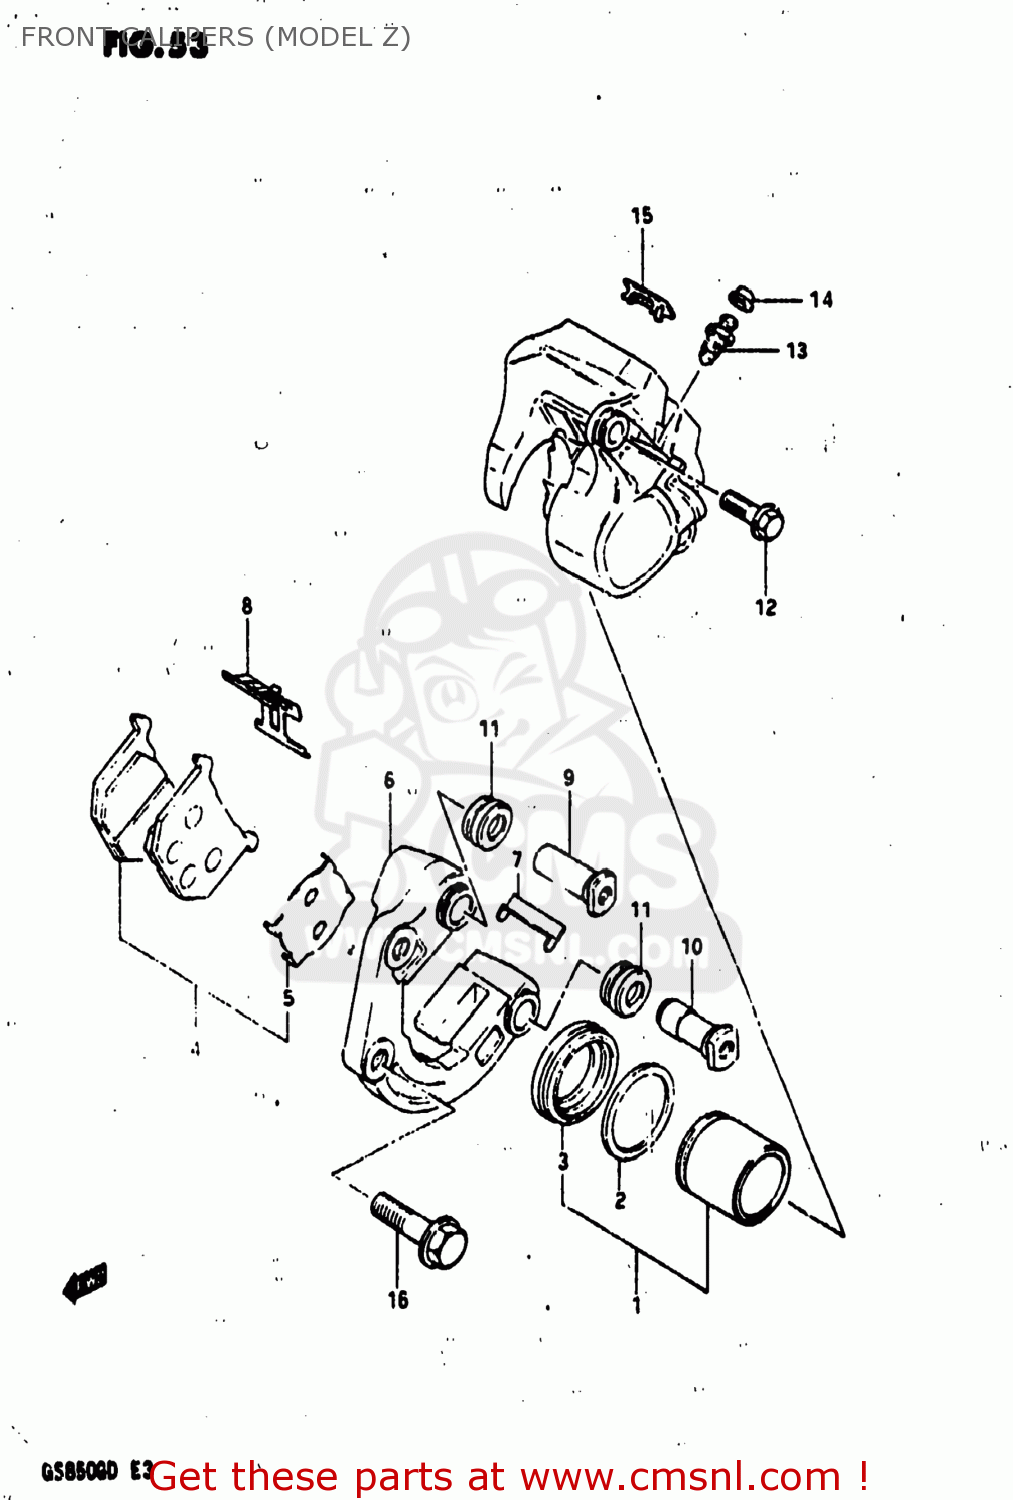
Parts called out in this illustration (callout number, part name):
0	CALIPER ASSEMBLY,FRONT,LEFT
1	PISTON SET
2	SEAL,PISTON
3	BOOT,PISTON
4	PAD SET (MCA)
5	SHIM,PAD
6	CARRIER,CALIPER,LEFT
7	GUIDE,PAD
8	SPRING,PAD
9	AXLE NO.1
10	AXLE NO.2
11	BOOT,AXLE
12	BOLT,CALIPER HOUSING
13	BLEEDER
14	CAP,BREATHER
15	COVER,INDICATOR
16	BOLT(10X37)
